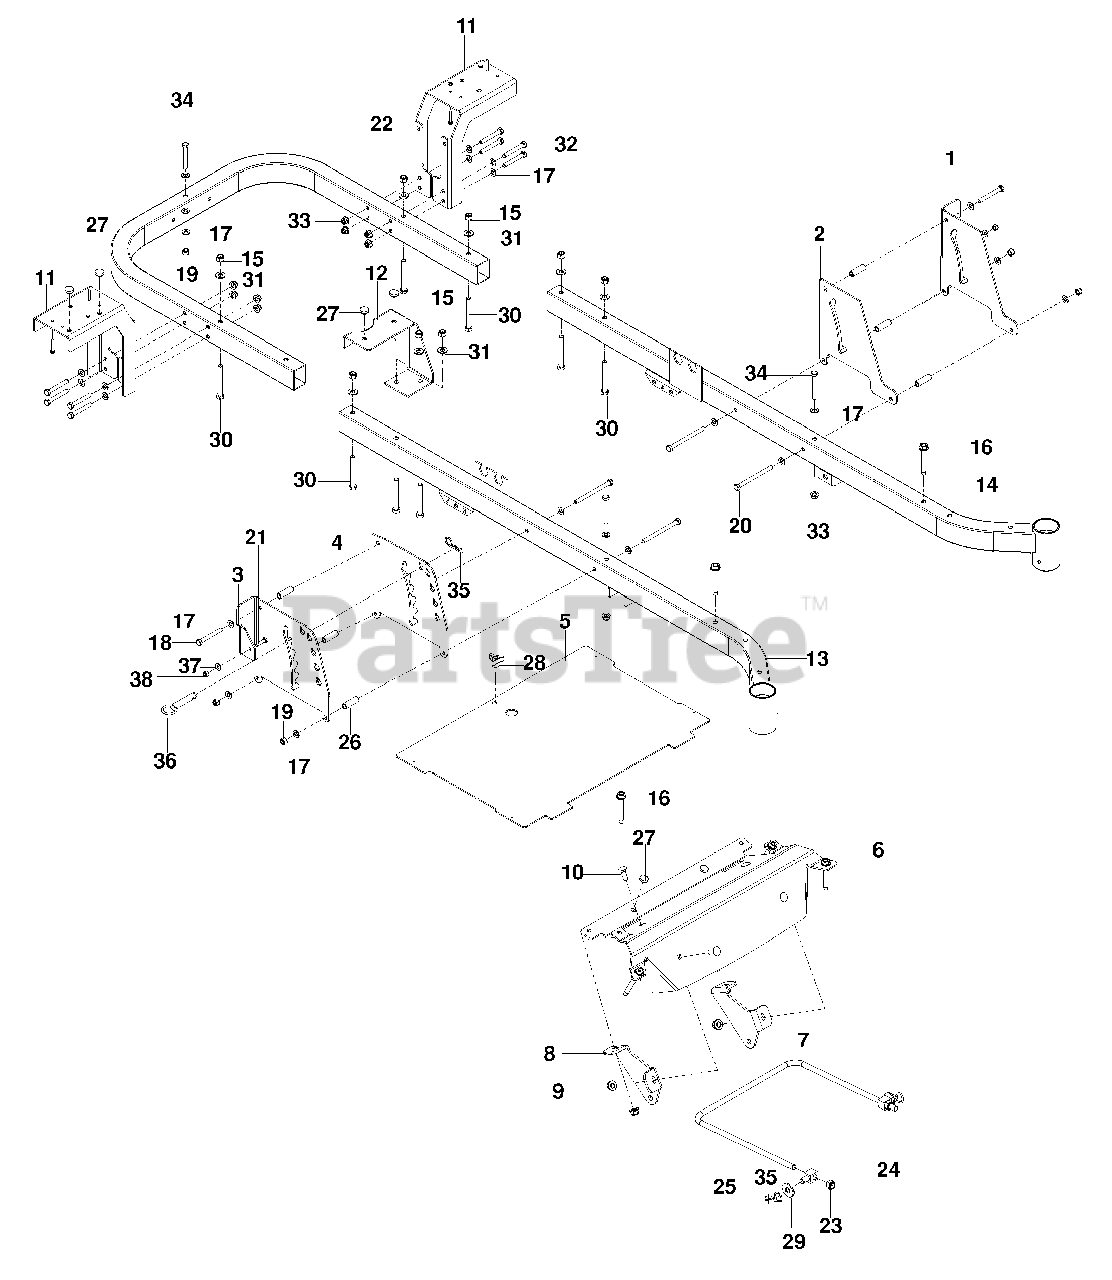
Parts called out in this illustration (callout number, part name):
1	PLATE, OUTER BRAKE
2	PLATE, BRAKE LATCH
3	PLATE, DECK HEIGHT
4	PLATE, DECK HEIGHT
5	FOOT PLATE w/DECALS
7	MOUNT, STRUT, RT, BLK
8	MOUNT, STRUT, LT, BLK
9	NUT 3/8-16 HEX FLG NYLOC
10	RHSNB 3/8-16 x 1
11	SUPPORT, FENDER
12	SUPPORT, TANK
13	FRAME, FRONT RT
14	FRAME, FRONT LT
15	NUT 3/8-16 HEX NYLOC
16	BOLT 3/8-16 x 25/8 THD FRM
17	WASHER 5/16 SAE FLT
18	HCS 5/16-18 x 2 1/2
19	NUT 5/16-18 HEX NYLOC
20	HCS 5/16-18 x 4
21	HCS 1/4-20 x 1
22	SCREW 10-12 x 1 1/4 WSH HD
23	NUT 7/16-14 HEX NYLOC
25	LINK, FRONT SUSPENSION
26	SPACER 1/2 OD x 1 1/2
27	GROMMET, BUMPER
28	KNOB w/STUD
29	WASHER 1/2 FLT
30	HCS 3/8-16 x 3
31	WASHER 3/8 SAE FLT
32	HCS 5/16-18 x 2 1/4
33	NUT 5/16-18 FLANGE NYLOC
34	HCS 5/16-18 x 2 3/4
37	WASHER 1/4 FLT SAE
38	NUT 1/4-20 HEX NYLOC
